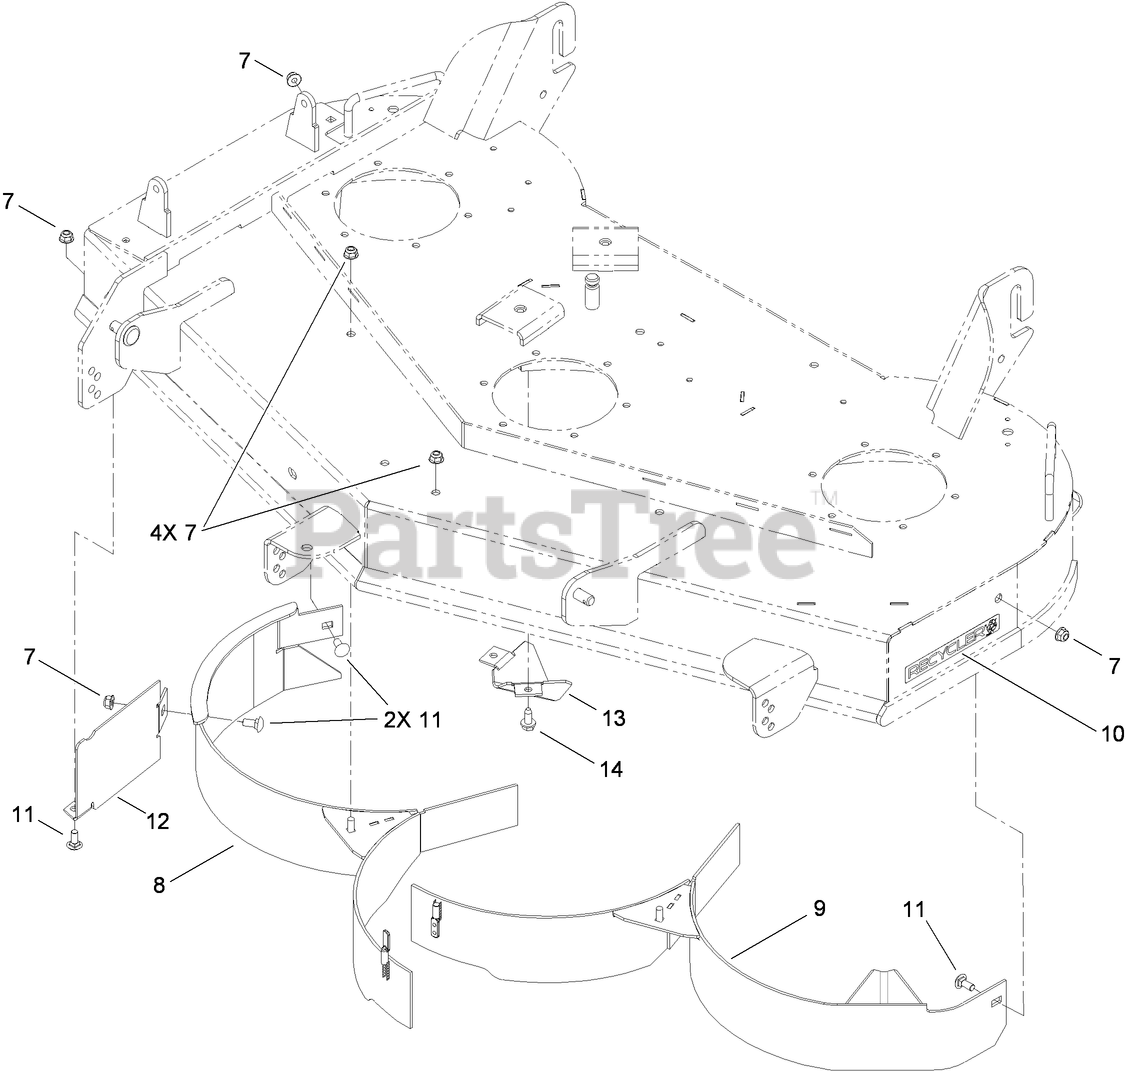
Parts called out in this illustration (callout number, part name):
7	NUT-HF, NI
8	RH BAFFLE ASM
9	LH BAFFLE ASM
10	DECAL-RECYCLER
11	BOLT-CARR
12	GUARD-BAFFLE
13	KICKER-FLANGED
14	SCREW-HWHTF
